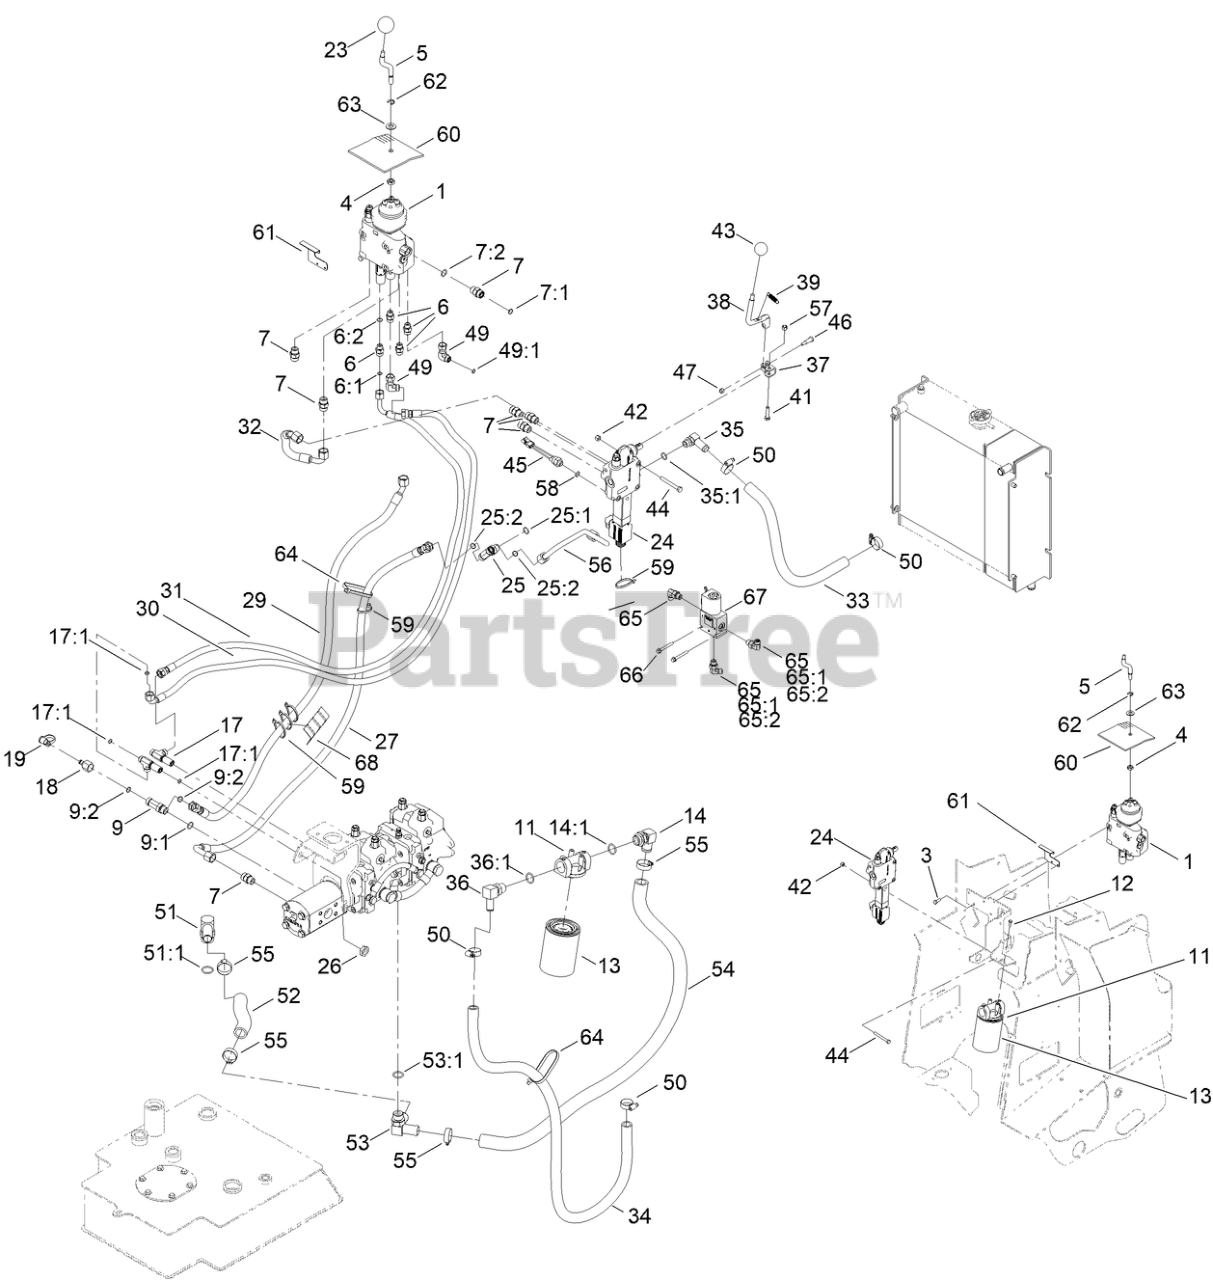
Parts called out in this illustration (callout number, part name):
1	2 SPOOL VALVE ASM
3	SCREW-HH
5	SHAFT-HANDLE, LIFT/TILT
6	FITTING-STRAIGHT
6:1	O-RING
6:2	O-RING
7	FITTING-STRAIGHT
7:1	O-RING
7:2	O-RING
9	FITTING-TEE
9:1	O-RING
9:2	O-RING
11	HEAD-FILTER
12	SCREW-HH
13	FILTER-OIL
14	FITTING-90
14:1	O-RING
17	FITTING-TEE, BULKHEAD
17:1	O-RING
18	FITTING
19	CAP-DUST
24	DOUBLE DETENT VALVE ASM
25	FITTING-HYD, TEE
25:1	O-RING
25:2	O-RING
26	NUT-LOCK
27	HYD HOSE ASM
29	HYD HOSE ASM
30	HYD HOSE ASM
31	HYD HOSE ASM
32	HYD HOSE ASM
33	HOSE-RETURN
34	HOSE-RETURN
35	FITTING-ELBOW, 90
35:1	O-RING
36	FITTING-ELBOW, 90
36:1	O-RING
37	BRACKET-AUXILARY
38	HANDLE ASM
39	SPRING-EXTENSION
41	SCREW-HH
42	NUT-LOCK, NI
44	SCREW-HH
45	SWITCH-BALL
46	BOLT-SHOULDER
47	NUT-LOCK, NI
49	FITTING-HYD, 90 DEG
49:1	O-RING
50	CLAMP-HOSE
51	FITTING-HYD, 90 DEG
51:1	O-RING
52	HOSE-SUCTION
53	CONNECTOR
53:1	O-RING
54	HOSE-RETURN
55	CLAMP-HOSE
56	HYDRAULIC TUBE ASM
57	NUT-LOCK, NI
58	O-RING
59	TIE-CABLE
60	DEFLECTOR-AIR
61	BRACKET-DEFLECTOR
62	RING-RETAINING
63	WASHER-PIVOT
64	TIE-CABLE
65	FITTING-ELBOW, 90 DEG
65:1	O-RING
65:2	O-RING
66	SCREW-HHF
67	SOLENOID VALVE
68	PROTECTOR-HOSE
